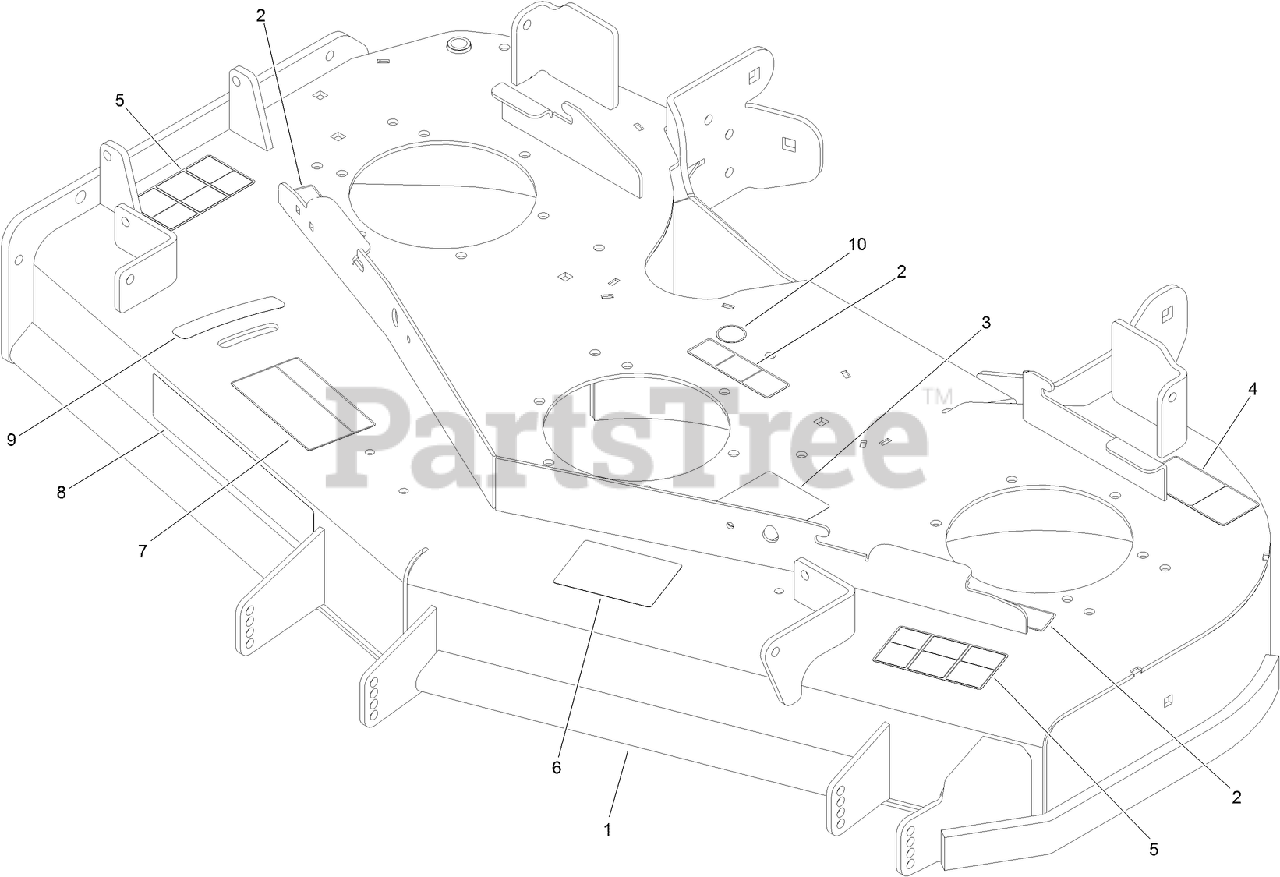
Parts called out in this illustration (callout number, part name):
1	DECK DECAL ASM
2	DECAL-COVER, MISSING
3	DECAL-ROUTING, DECK BELT
4	DECAL-TORQUE, BLADE BOLT
5	DECAL-DANGER
6	DECAL-SCALP, ANTI
7	DECAL-ADJUSTMENT, BAFFLE
9	DECAL-SETTING, BAFFLE
10	DECAL-GREASE
